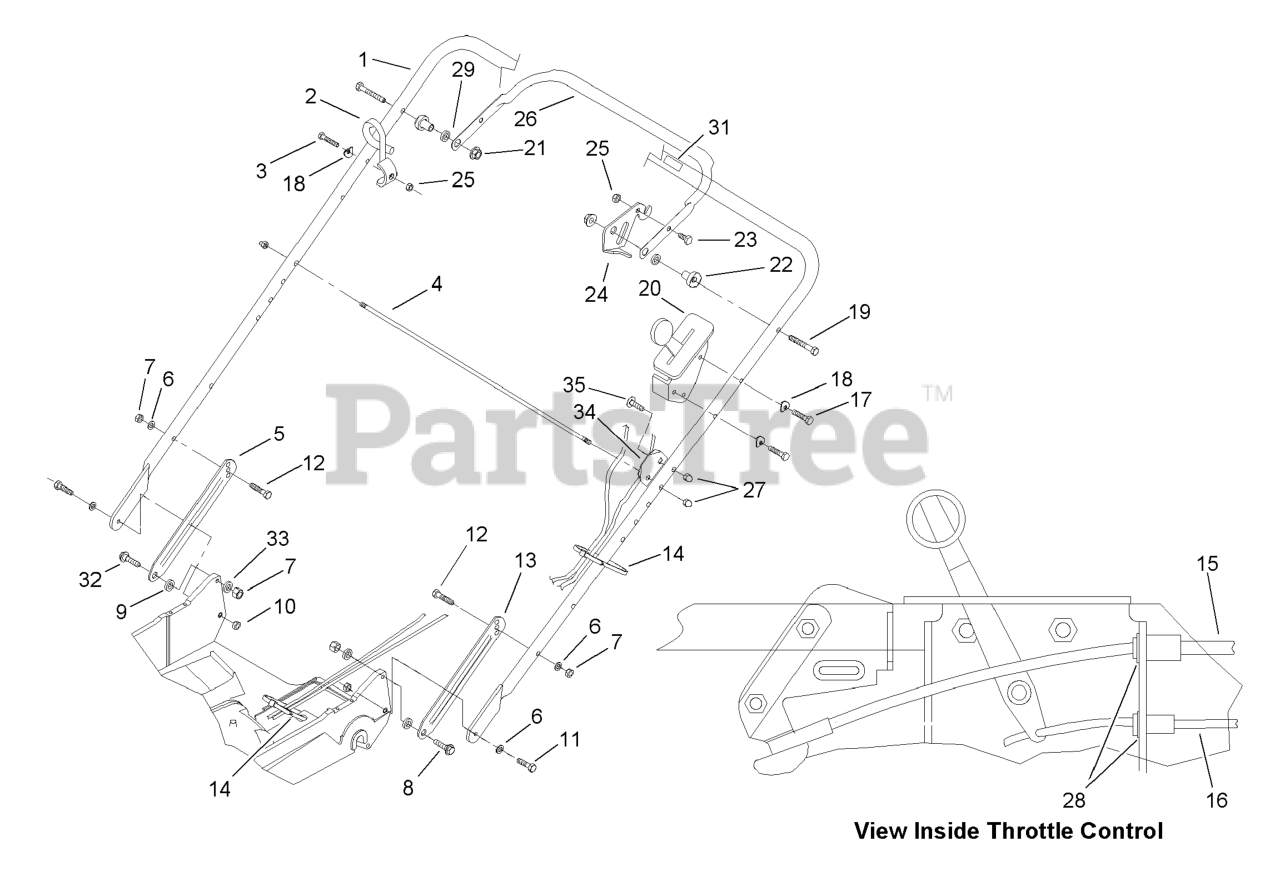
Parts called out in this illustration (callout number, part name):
2	GUIDE-ROPE
3	SCREW-HH
4	ROD-SUPPORT, BAG
6	WASHER-BELLEVILLE
7	NUT-LOCK, NI
8	SCREW-SHOULDER
9	SPACER
10	NUT-LOCK, NI
11	SCREW-HH
12	SCREW-HH
14	TIE-CABLE
15	CABLE-BRAKE
17	SCREW-HH
18	WASHER
19	SCREW-HH
21	NUT-LOCK, NI
22	SPACER-SUPPORT
23	SCREW-HH
24	LEVER-CONTROL
25	NUT-LOCK, NI
26	BAR-CONTROL
27	NUT-CAP
29	SPACER-NYLON
31	DECAL-PROTECTION, HEARING
32	SCREW-SHOULDER
33	WASHER-PLAIN
35	SCREW-CARR
